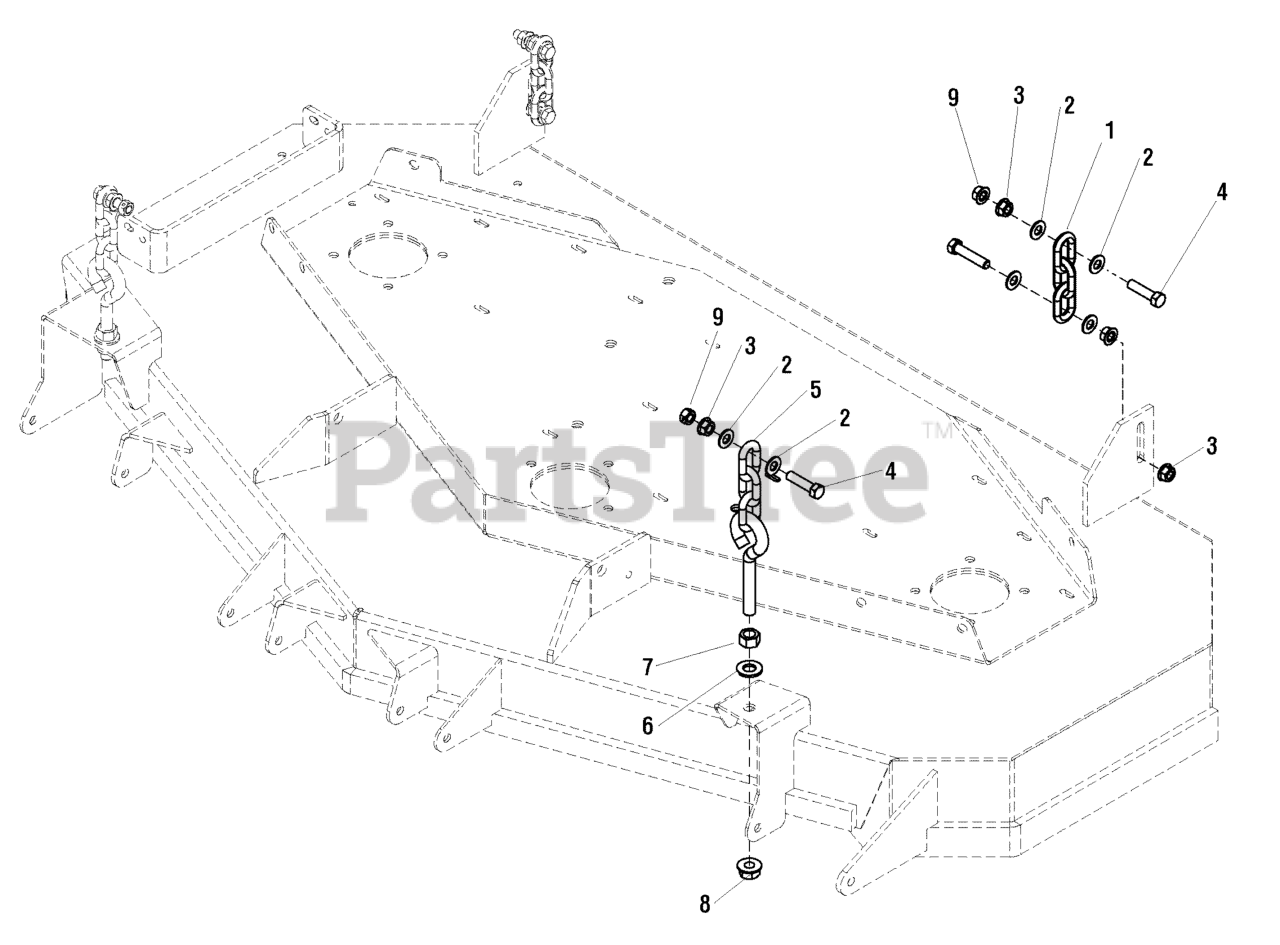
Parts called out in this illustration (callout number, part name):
1	CHAIN, 5/16" GD30, 3 LINKS
2	WASHER, 3/8 SAE
3	NUT, 3/8-16 HEX LG. SERR FLG
4	BOLT, 3/8-16 X 1-3/4" GD5 CZ
5	HANGER, FRONT DECK-3LINK, 5.5" EB
6	WASHER, 1/2 SAE
7	NUT, HEX 1/2-13
8	NUT, Hex Flange, Nylock, 1/2-13
9	NUT, 3/8-16 HEX SIDE LOCK
